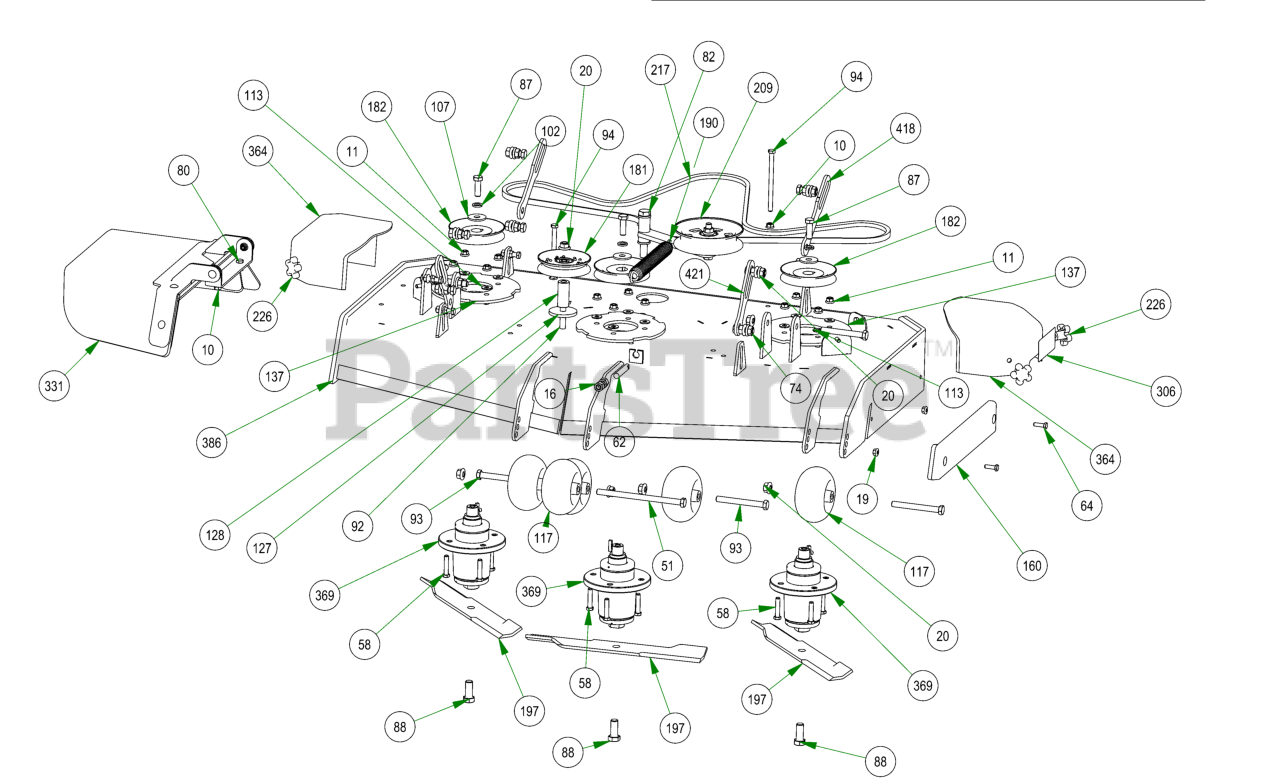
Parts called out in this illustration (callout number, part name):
10	3/8-16 HEX SERRATED FLANGE NUT HARD/ZINC
11	3/8-16 NYLON INSERT FLANGE LOCKNUT (GR.F) ZINC
13	5/8-11 NYLON INSERT JAM LOCKNUT ZINC
16	1/2-13 HEX NUT ZINC
19	5/16-18 NYLON INSERT FLANGE LOCKNUT ZINC
20	1/2-13 NYLON INSERT FLANGE LOCKNUT ZINC
51	1/2-13 X 8 HEX CAP SCREW GR 5 ZINC
58	3/8-16 X 1-3/4 HEX C/S (GR.5) ZC
62	All Thread
64	5/16-18 X 1 HEX CAP SCREW (GR.5) ZINC
74	1/2-13 X 1-1/2 HEX CAP SCREW (GR.5) ZINC
75	1/2-13 X 4 HEX CAP SCREW (GR.8) ZINC YELLOW
80	3/8-16 X 3/4 HEX CAP SCREW (GR.5) ZINC
82	5/8-11 X 4 HEX CAP SCREW (GR.8) ZINC YELLOW
87	1/2-20 X 1-1/2 HEX CAP SCREW (GR.5) ZINC
88	5/8-18 X 1-1/2 HEX CAP SCREW (GR.8) ZINC YELLOW
92	1/2-13 X 4-1/4 HEX CAP SCREW (GR.5) ZINC
93	1/2-13 X 4-1/2 HEX CAP SCREW (GR.5) ZINC
94	3/8-16 X 5-1/2 HEX CAP SCREW (GR.5) ZINC
98	5/16-18 X 1 CARRIAGE BOLT (GR.8) ZINC
102	1/2 SPLIT LOCKWASHER (GR.8) ZINC/YELLOW
105	5/8 USS FLAT WASHER (1-3/4" OD) GR.8 ZINC YELLOW
106	.635 ID X 1.120 OD X .140 THICK FLAT WASHER NYLON
107	1/2 BELLEVILLE WASHER (1-5/8 OD X .140 THK) ZINC
110	.360 ID X .983 OD X .120 THICK FLAT WASHER NYLON BLACK
113	5/16 USS FLAT WASHER (7/8 OD) ZINC
117	2019 Deck Wheel
127	MZ Deck Idler Spacer
128	2019 Revolt Stationary Idle Spacer
137	Deck Spindle Support Plate
160	REVISED TRIM BUMPER_20180226
163	5/16-24 X 1/4 SOCKET SET SCREW (CUP PT) PLAIN
181	4 3/4 Idler Pulley - ABFI-76
182	5" Spindle Deck Pulley
190	2019 Outlaw Gen2 Deck Spring
197	48" ZT/Mav/Compact Outlaw Blade with Fusion
209	2019 Revolt Deck Idler Assembly
223	1/4 X 1 SQ MACHINERY KEY 1018 STL PLN
226	5/16" Knob
229	Turnbuckle
246	1.02 ID X 1.38 OD X .250 THK SPACER ZINC
302	2018 48" Deck Decal
306	Danger Decal-Spindle/Discharge
313	2019 Revolt Deck Belt Route Decal
326	Deck Impact Patent Decal 9591803
331	2019 Outlaw Gen2 Chute Assembly
364	2023 Revolt pulley cover
365	R Series Rubber For Deck
366	61 Bolt in Baffle Deck v2 Stripping Plate
369	OUTLAW SPINDLE ASSEMBLY
386	2023 48'' DECK
418	2023 Stand-On Rear Deck HangerV2
421	Deck Hangar
